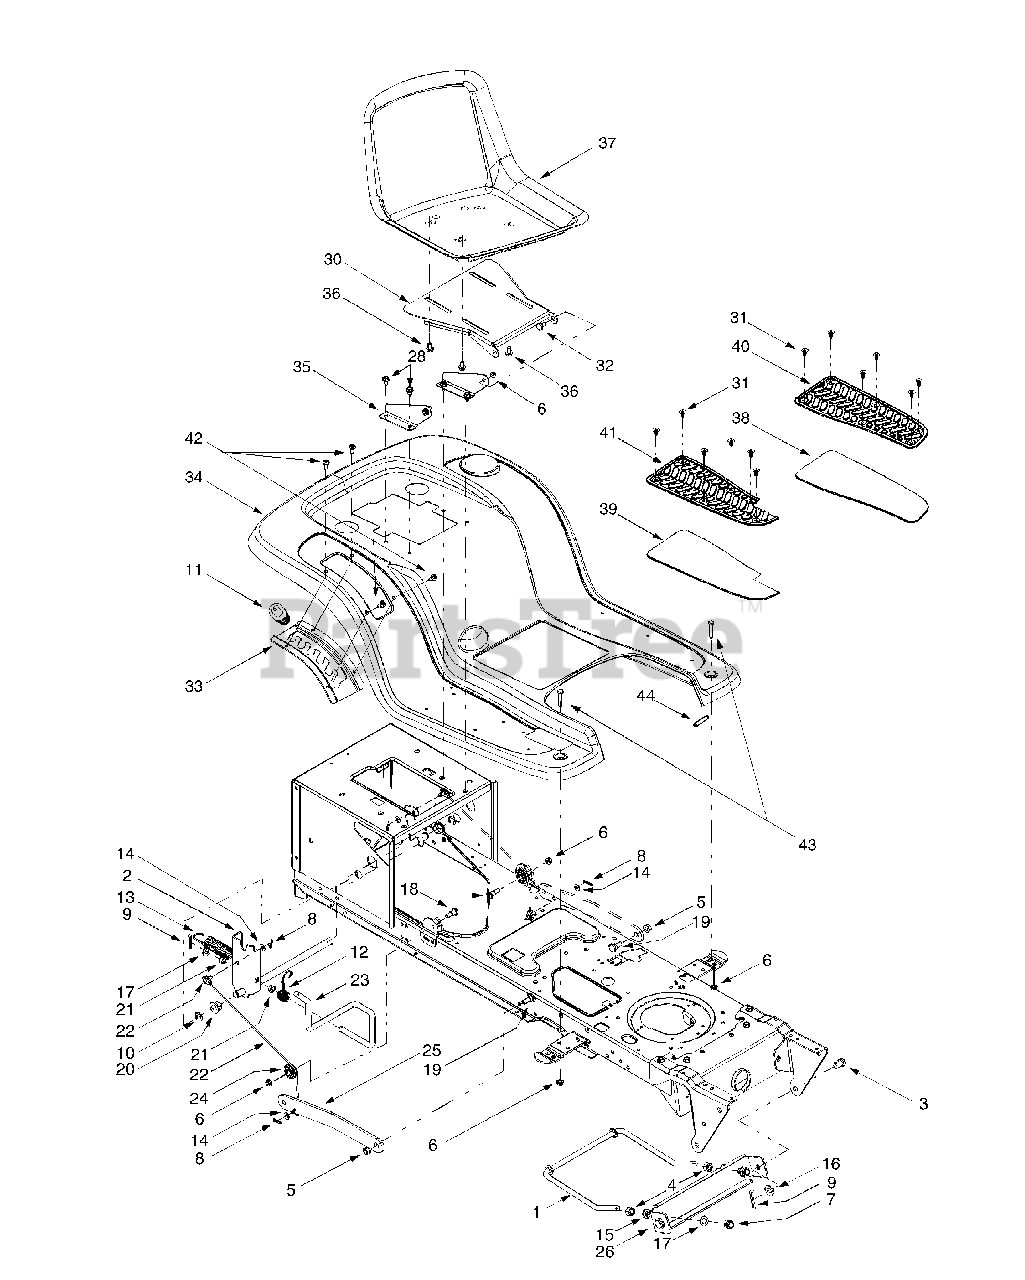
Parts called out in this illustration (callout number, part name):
3	Clevis Pin, .5 x .78
4	Hex Nut, 1/2-13
5	Flange Lock Nut, 3/8-16
6	Flange Lock Nut, 5/16-18
7	Hex Nut, 1/2-13
8	Internal Cotter Pin
9	Cotter Pin
10	E-ring
11	Handle Grip
12	Torsion Spring
13	Lift-assist Spring, 1.15 x 5.99
14	Flat Washer, 5/16
15	Lock Washer, 1/2
16	Flat Washer, .31 x 1.062 x .134
17	Flat Washer, .51 x 1.12 x .06
18	Hex Cap Screw, 5/16-18 x .62
19	Shoulder Screw, .5 x .27, 3/8-16
20	Hex Flange Bearing
21	Snap Flange Bearing
22	Lift Cable, 16.16
23	Lift Handle
24	Roller Pulley
28	Self-tapping Screw, 5/16-18 x .625
32	Shoulder Screw, .437 x 1.62
36	Hex Washer Head Screw, 3/8-16 x .625
37	Seat, Medium Back
38	LH Abrasive Foot Pad
39	RH Abrasive Foot Pad
40	LH Rubber Foot Pad
41	RH Rubber Foot Pad
42	Self-tapping Screw, 5/16-18 x .75
43	Hex Cap Screw, 5/16-18 x .62
44	Trim Strip, 1.5
